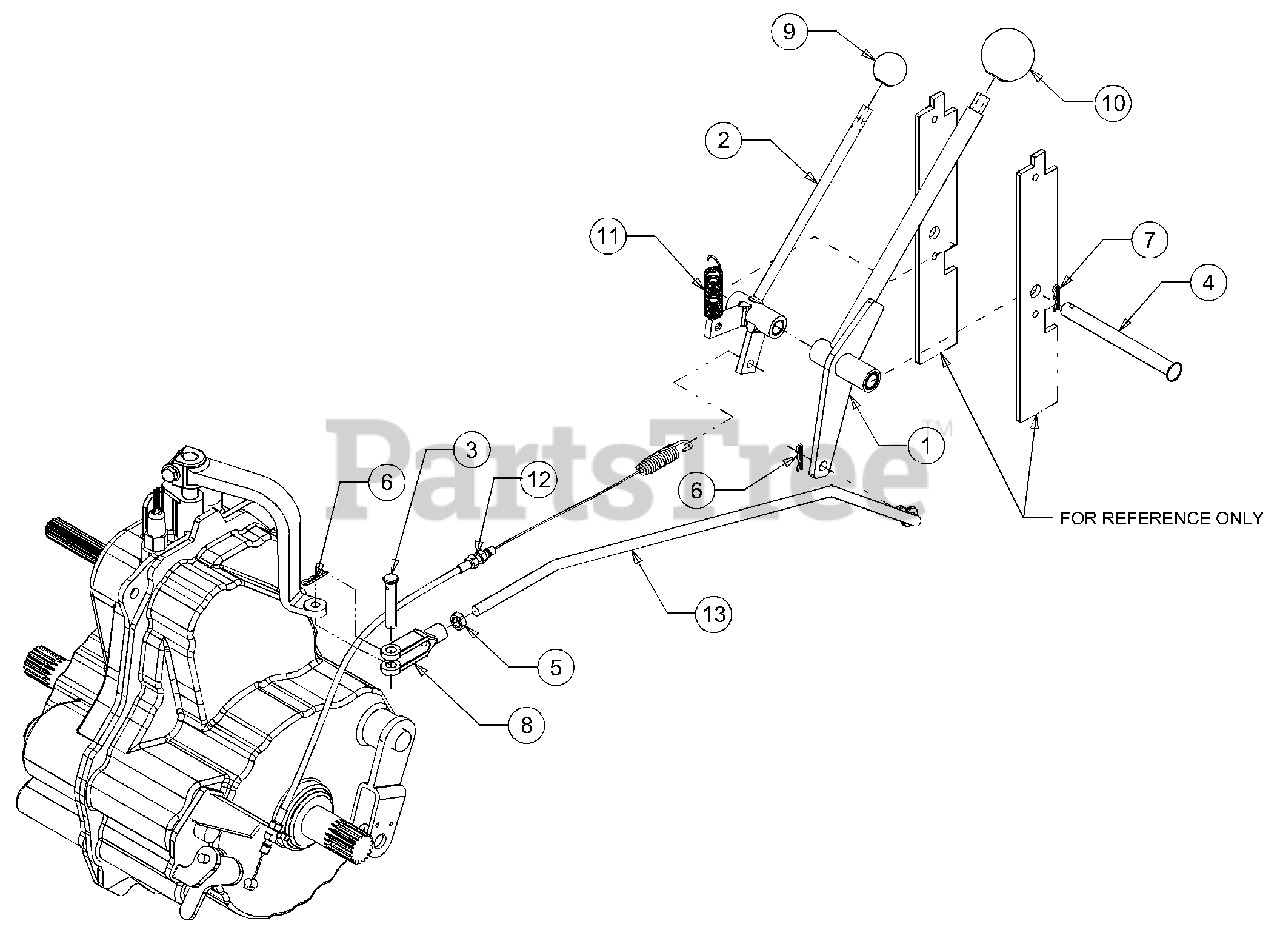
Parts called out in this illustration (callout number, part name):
1	Lever Assembly, Transmission
2	Shifter Assembly, Differential Lock
3	Pin, Clevis, .375 x 2.0
4	Pin, Clevis, .5 x 5.375
5	Nut, Jam, 3/8-24
6	Pin, Cotter, .072 x 1.13
7	Pin, Cotter, 1/8 x 1.0
8	Clevis, Adjustment
9	Knob, Ball
10	Knob, Ball
11	Spring, Extension, .637 x 2.972
12	Control Cable, Differential Lock
13	Shifter Rod, Transmission
